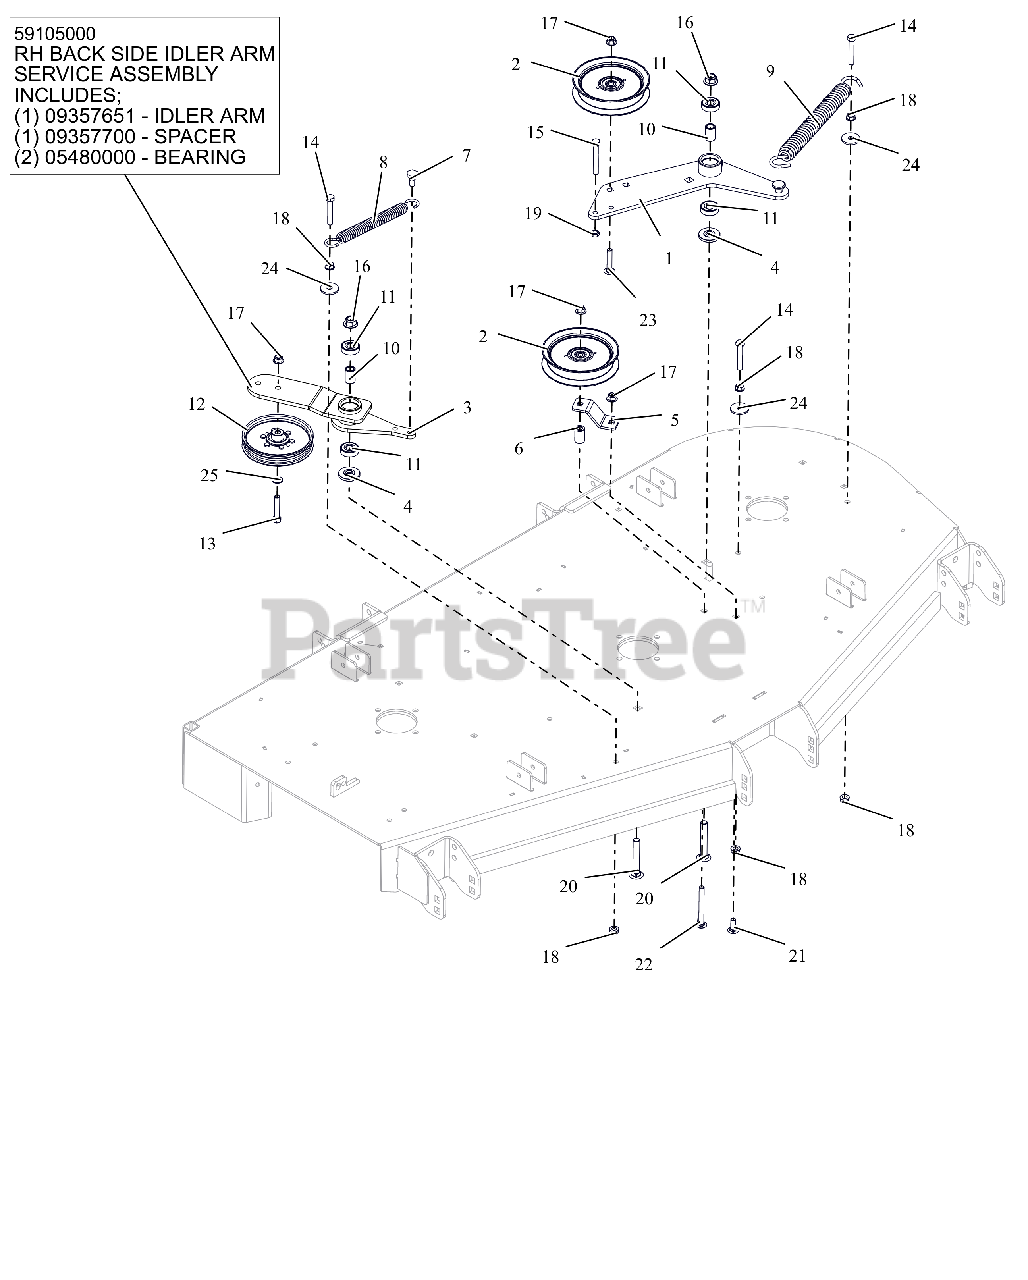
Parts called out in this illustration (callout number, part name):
1	DECK PTO IDLER ARM WLDMT - BLK
2	IDLER, FLAT 5.00"
3	DECK RH IDLER ARM WMT - BLK
3	RH BACKSIDE IDLER ARM ASSEMBLY
4	SPACER, IDLER ARM
5	PTO FIXED IDLER MTG BRKT -RED
6	BUSHING, SLV .380X.750X1.190
7	BLT,SHLDR EP .38-16X.30 HEX YZ
8	SPRING, EXTENSION
9	SPRING, EXTENSION
10	SPACER .510 X .75 X 1.1485
11	BRG-BALL .500X1.38X.437
12	PULLEY, FLAT IDLER
13	BLT,HEX .38-16X2.00 G5 ZCC
14	BLT,HEX .38-16X2.25 G5 ZCC
15	BLT, HEX .38-16X2.75 G5 ZCC
16	NUT,NYL-FLG .50-13 GF ZCC
17	NUT,NYL-FLG .38-16 GF ZCC
18	NUT, SPNLK-FLG .38-16 G5 ZCC
19	NUT-JAM .375-16 G2 ZCC
20	BTL,RHSSN .500-13 X 3.25 G5 ZCC
21	BLT,RHSSN .38-16X1.00 G5 ZCC
22	BLT,RHSSN .38-16X3.50 G5 ZCC
23	BLT,RHSSN.375-16X2.00 G5 ZCC
24	WSHR,FLT .406X1.375X.135 ZCC
25	WSHR,FLT .406X.812X.065 ZCC
